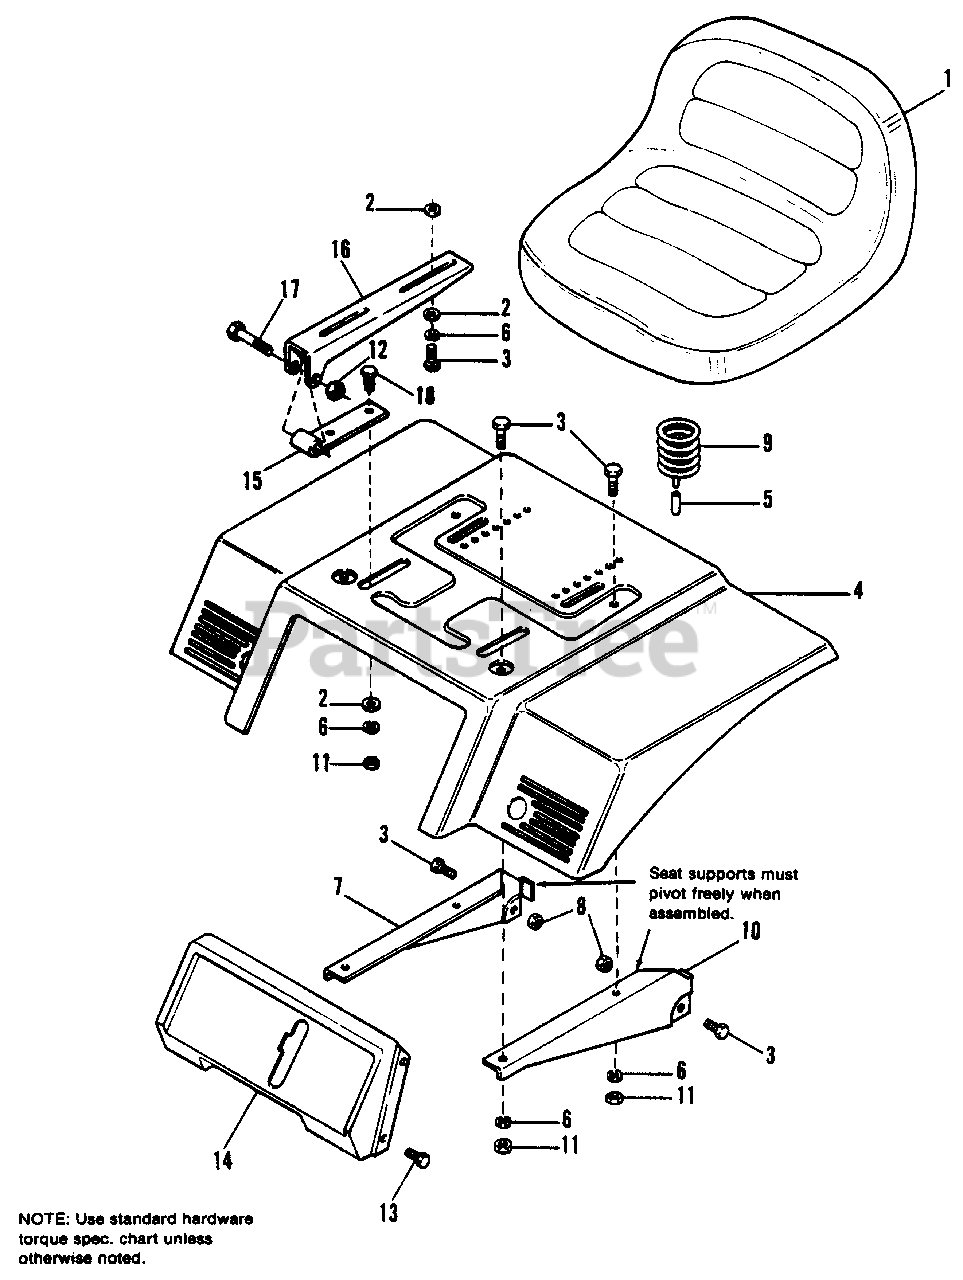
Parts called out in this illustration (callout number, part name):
2	WASHER, Plain, 5/16
3	CAPSCREW, Hex, 5/16-18 x 3/4
4	DECK, Seat
5	COVER, Wire
6	LOCKWASHER, 5/16
7	SUPPORT, Seat, R.H.
8	LOCKNUT, Hex, 5/16-18
9	SPRING, Seat
10	SUPPORT, Seat, L.H.
11	NUT, Hex, Full, 5/17-18
12	LOCKNUT, Hex, 3/8-16
13	SCREW, Hex, Taptite, 1/4-20 x 1/2
14	PANEL, Shift
15	HINGE, Lower
16	HINGE, Upper
17	CAPSCREW, Hex, 3/8-16 x 2
18	CAPSCREW, Hex, 5/16-18 x 1.0
